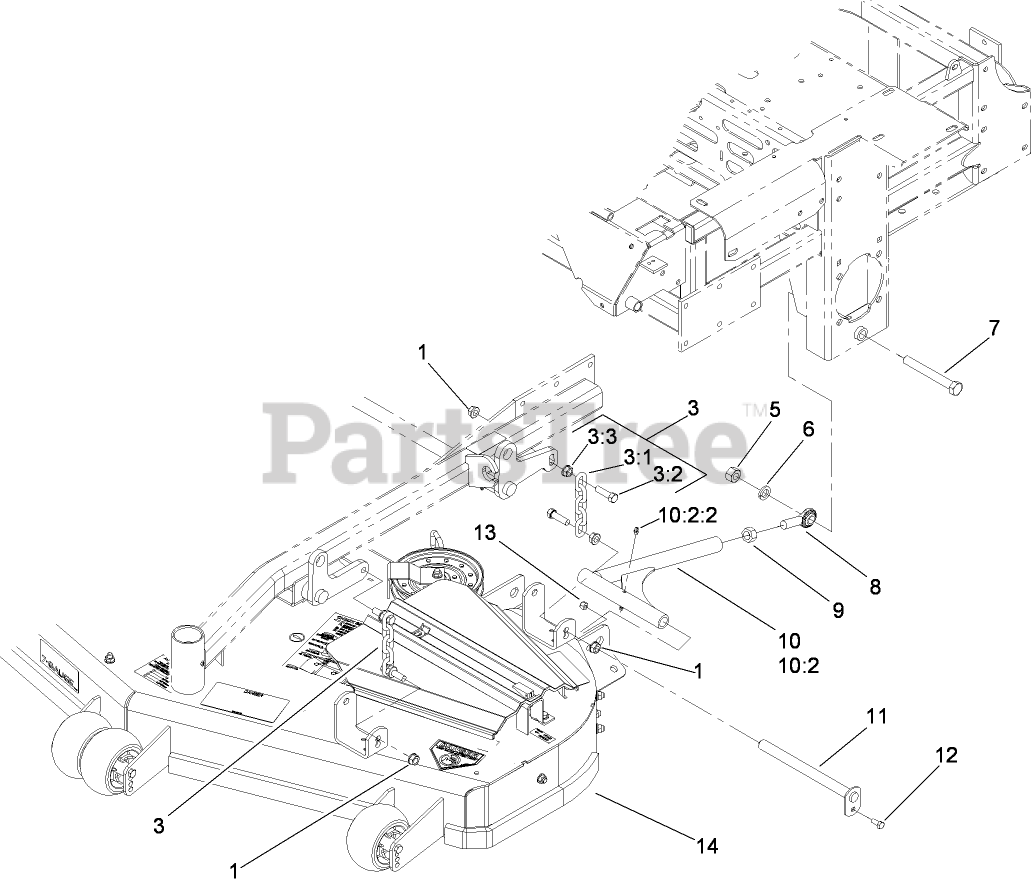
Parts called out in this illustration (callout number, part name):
1	NUT-HF
3	DECK CHAIN ASM
3:1	CHAIN-LIFT, DECK
3:2	SCREW-HH
3:3	NUT-HF
5	NUT-HEX
6	WASHER-LOCK
7	SCREW-HH
8	BALLJOINT-SPHERICAL
9	NUT-HEX
10	STRUT-DECK
10:2	TUBE AND ZERK ASM
10:2:2	FITTING-GREASE
11	PIN-STRUT
12	SCREW-HH
13	NUT-LOCK, NI
14	Deck ASM
